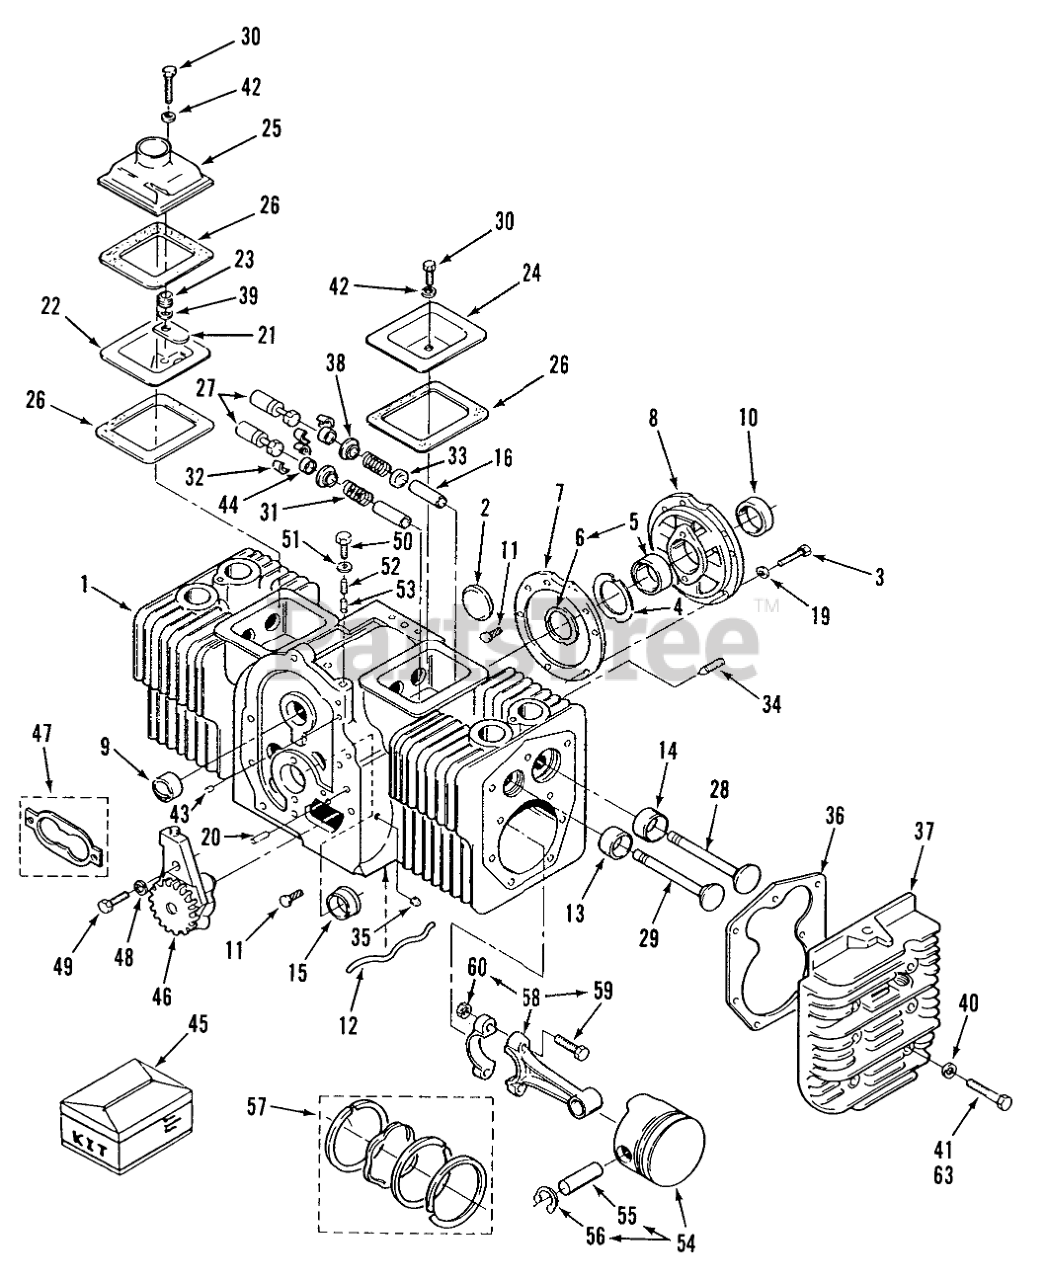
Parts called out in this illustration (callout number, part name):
1	Short Block
3	Screw Cap-Hex Hd.
4	Shim, Crankshaft End Play (.005)
5	Bearing, Crankshaft Rear Standard (Incl. Ref. #15)
6	Washer-Thrust
7	Gasket, Bearing Plate
8	Bearing Plate
9	Bearing, Camshaft
10	Seal, Oil-Crankshaft Rear
11	Pin, Drive-Bearing stop
12	Tube, Oil-Cylinder Block
13	GAS-LINE
14	Insert, Valve Seat-Intake (Standard)
15	Bearing, Crankshaft-Front(Flanged) Standard
16	Exhaust Valve Guide
19	Washer, Lock-Spring
20	Pin, Gear Cover Alignment
21	Reed-Breather Valve
22	Baffle, Breather Valve
23	Spring, Breather Valve
24	RH Valve Cover
25	LH Valve Cover
26	Gasket, Valve Cover
27	Tappet, Valve (Standard)
28	Intake Valve
29	Exhaust Valve
30	Screw-Cap Hex Hd.
31	Valve Spring
32	Spring Lock
33	Intake Valve Seal
34	Screw 3/8-16 x 5/8
35	Pipe Plug
36	SPACER
37	Right Cylinder Head
38	Retaining Washer
39	Washer, Flat
40	Washer, Flat
41	Special Bolt 2" long
42	Washer, Flat-Copper
43	Plug, Core Hole
44	NUT-RETAINER
45	Complete Engine Gasket Kit
46	Pump, Oil
47	Gasket Kit, Oil Pump
48	Spring Washer
49	Screw, Cap-Hex Hd.
50	Screw, Cap-Hex Head
51	Washer, Flat
52	Spring, By-Pass
53	Plunger, Bypass Valve
54	OIL PAN ASM
55	BRAKE DRUM ASM
56	Ring, Retaining
57	Ring Set, Piston-Standard
58	Rod w/Bolts and Nuts-STD
59	Bolt, Special-Connecting Rod
60	Nut, Hex-Crown Lock
63	Special Bolt 2.375" Long
